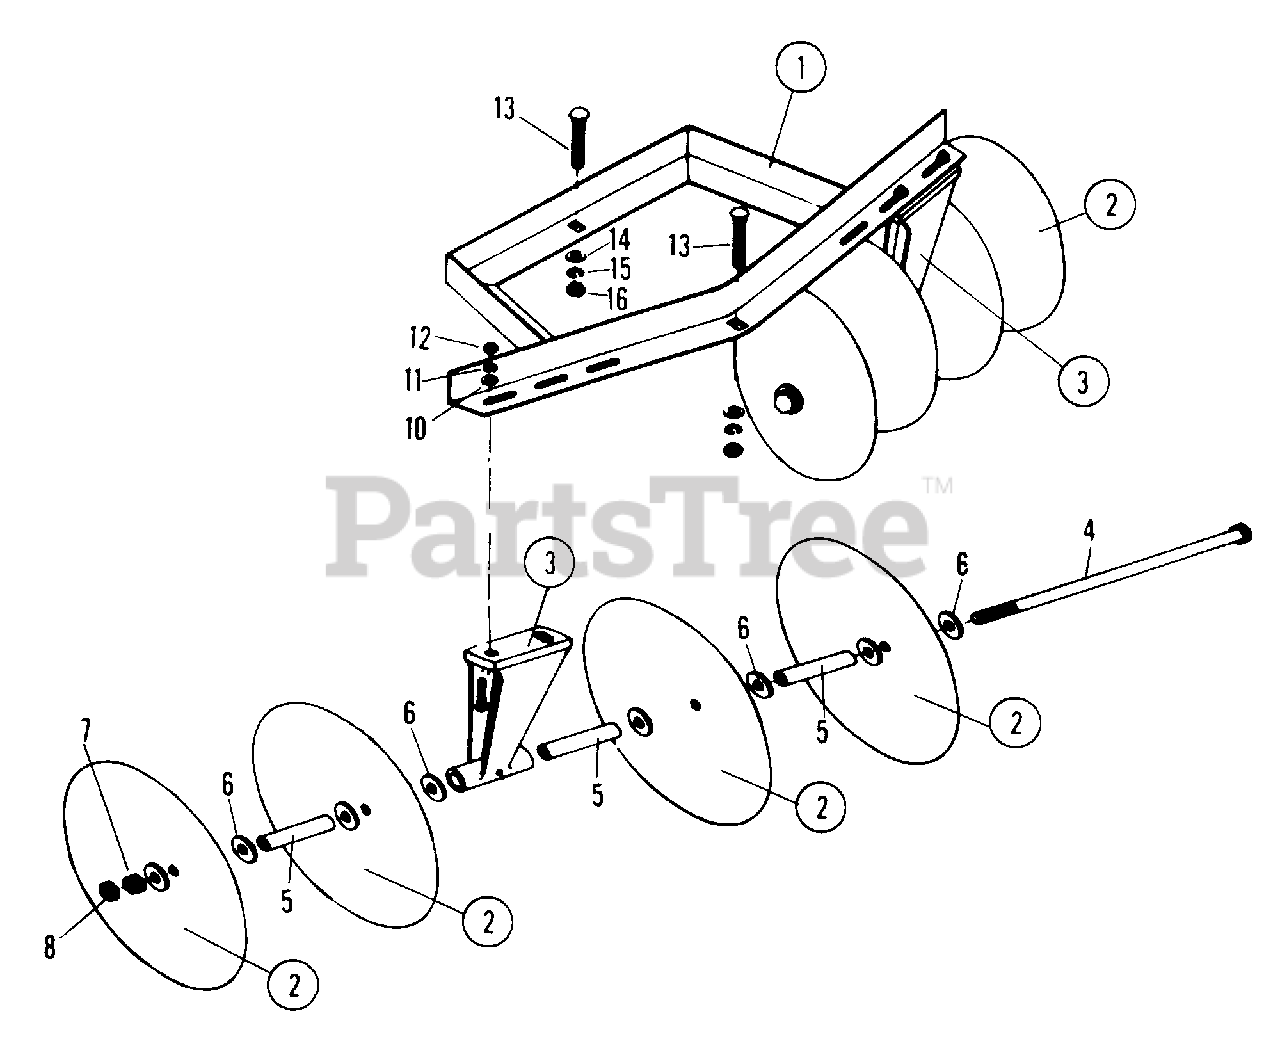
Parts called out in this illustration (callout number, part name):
1	FRAME, DISC HARROW
2	BLADE, DISC
3	HANGER, BEARING
4	GANG-BOLT, 3/4 x 16
5	SPACER, DISC BLADE
6	WASHER, 3/4" FLAT
7	NUT, 3/4 HEX
8	NUT, 3/4 HEX JAM
9	BOLT, 3/8 x 1-1/2 CARRIAGE
10	WASHER, 3/8" PLAIN
11	LOCKWASHER, 3/8"
12	NUT, 3/8 HEX
13	BOLT, 1/2 x 3-1/2 CARRIAGE
14	WASHER, 1/2 PLAIN
15	LOCKWASHER, 1/2"
16	NUT, 1/2 HEX
